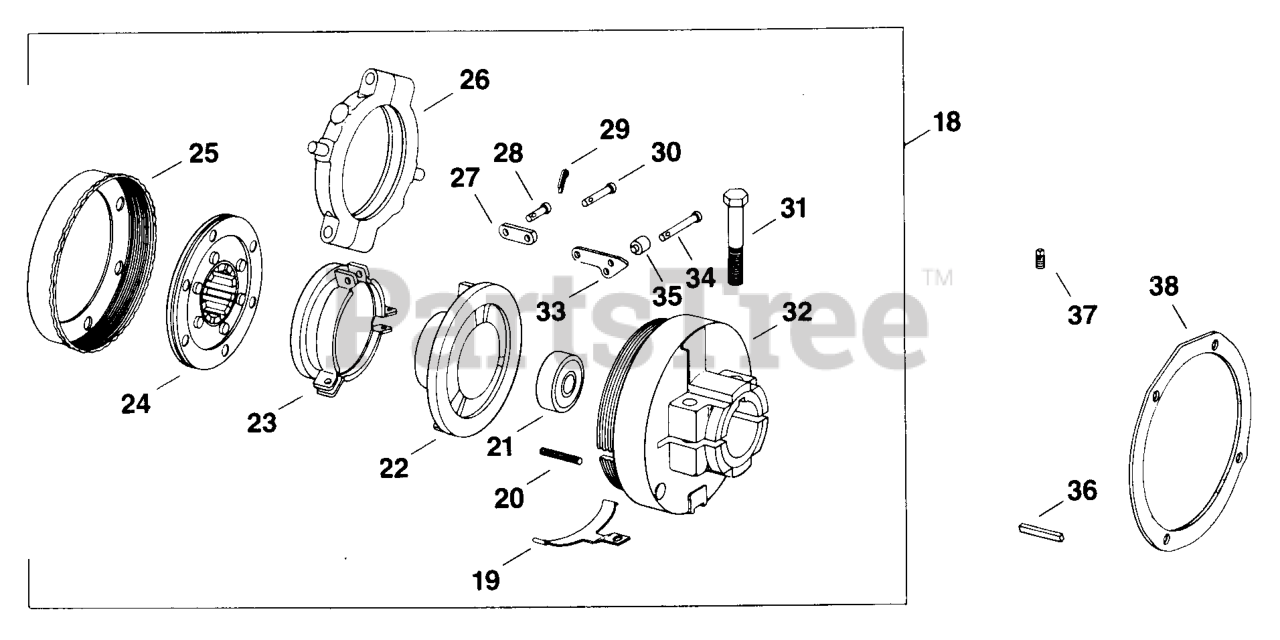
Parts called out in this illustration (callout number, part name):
18	Clutch - assembly (See pg. 29)
20	SPRING - DISCONTINUED
21	BEARING
23	SLEEVE - DISCONTINUED
24	MEMBER - DISCONTINUED
25	RING - DISCONTINUED
27	LINK - DISCONTINUED
30	PIN - DISCONTINUED
31	Screw
32	HOUSING - DISCONTINUED
33	LEVER - DISCONTINUED
34	PIN - DISCONTINUED
35	ROLLER - DISCONTINUED
36	KEY - DISCONTINUED
37	PLUG-DISCONTINUED
4814102-S	RING, SNAP - DISCONTINUED
